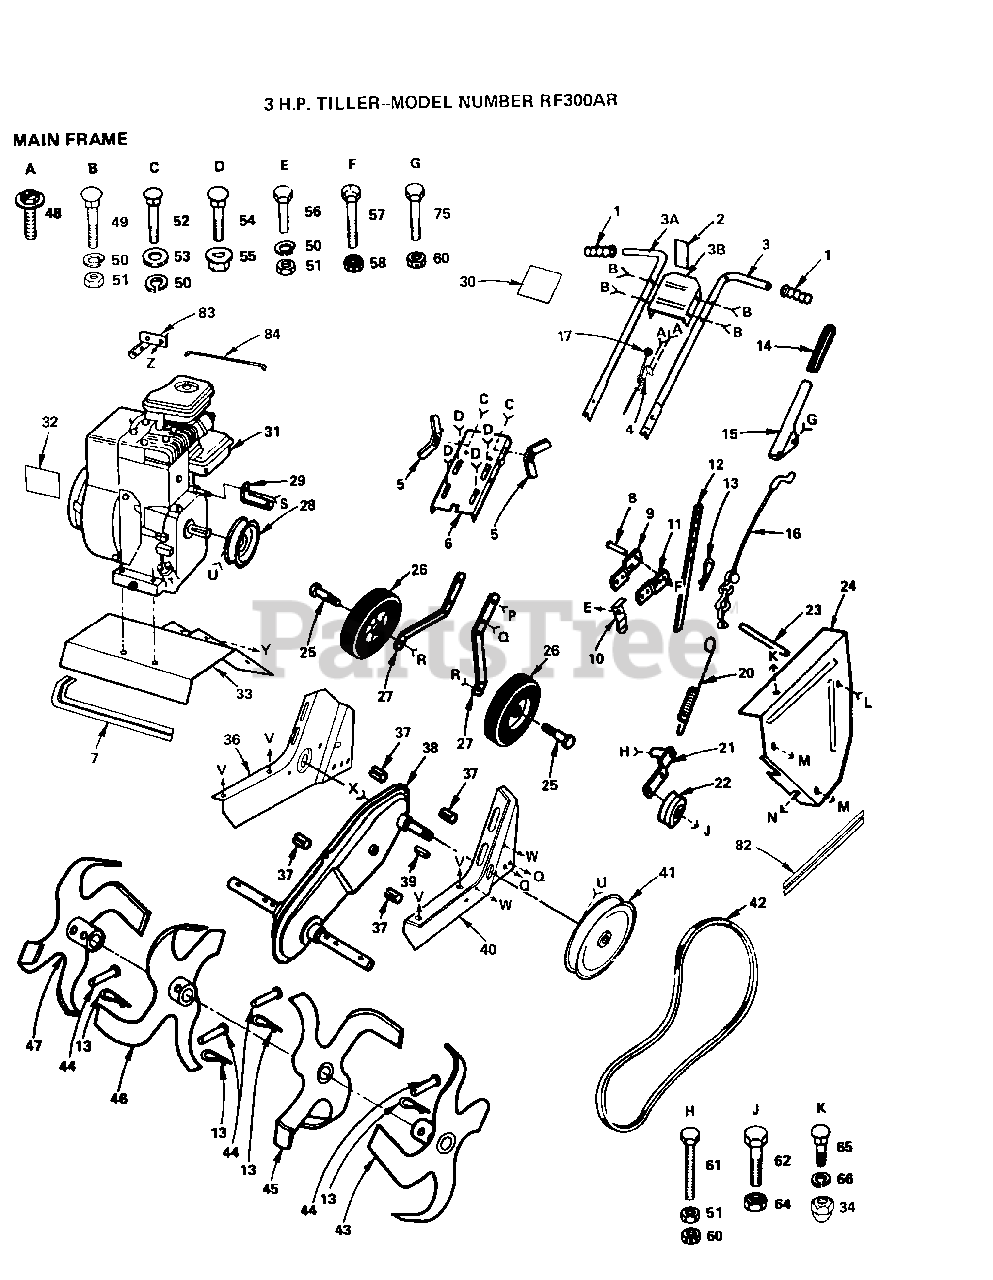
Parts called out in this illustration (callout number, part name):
3B	BRACKET - HANDLE
4	THROTTLE CONTROL
7	DECAL - TINE SHIELD
8	DRILLED RIVET RT
10	STAKE SPRING CT
13	SPRING.RETAINER
14	GRIP T
20	SPRING EXT TI
23	SPLIT SPACER
25	BOLT M
31	ENGINE, B&S
33	SHIELD - TINE
34	NUT-CAP TI
36	ENGINE BRACKET
37	SPLIT SPACER RT
39	KEY T
40	ENGINE BRACKET
41	TRANS SHEAVE RT
44	DRILLED RIVET RT
48	SCREW TI
50	LOCKWASHER
51	NUT.HEX.5/16-18
52	BOLT
53	WASHER
55	NUT
56	BOLT
58	GRIPCO NUT
64	NUT
65	BOLT
66	LOCKWASHER
75	BOLT.HEX.5/16-1.5
82	DECAL - BELT GUARD
